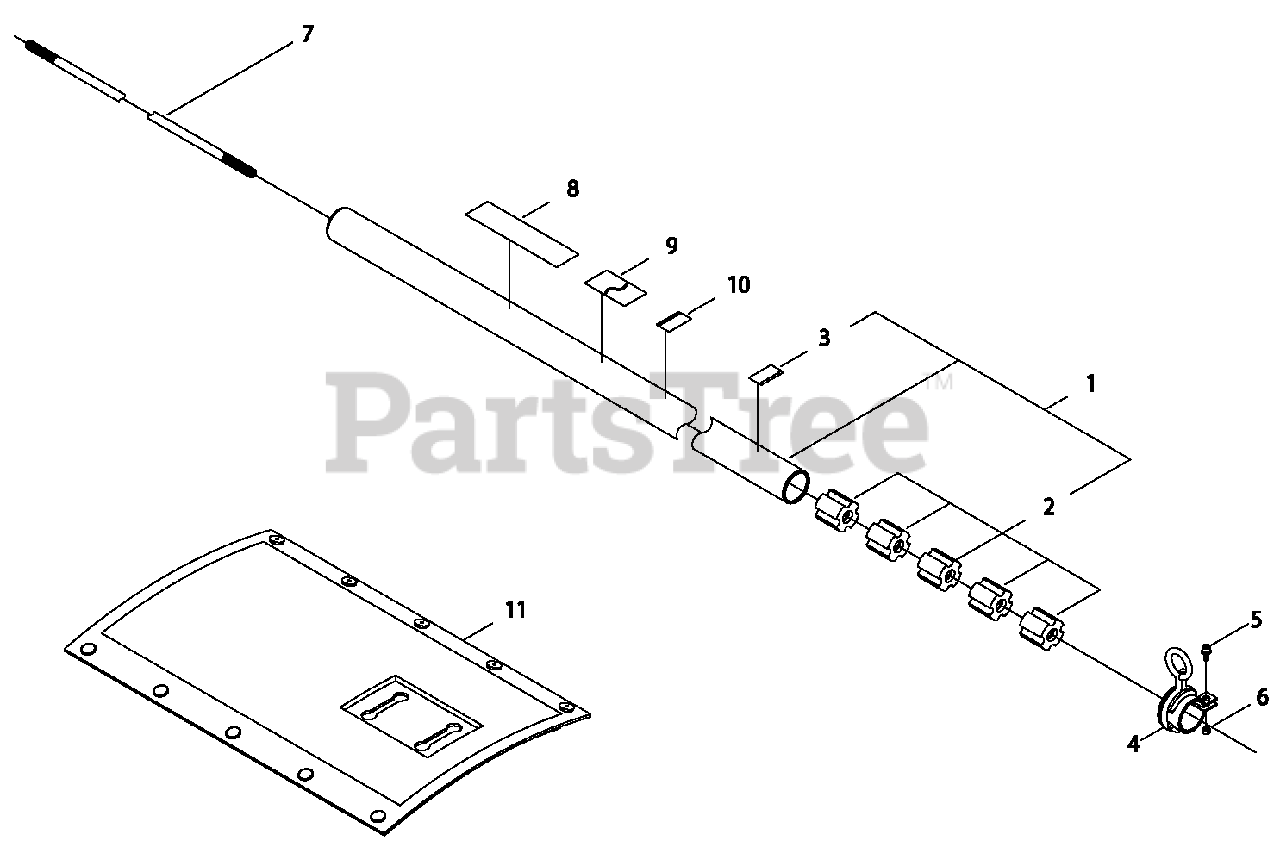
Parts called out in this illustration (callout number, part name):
1	MAIN PIPE ASSY
2	BUSHING
3	LABEL - ALIGNMENT
4	HANGER
5	BOLT M5×12
6	NUT M5
7	DRIVESHAFT
8	LABEL, SHINDAIWA PROFESSIONAL
9	LABEL, CAUTION (BLADE CAPABLE)
10	LABEL, HANDLE
11	PROTECTOR
